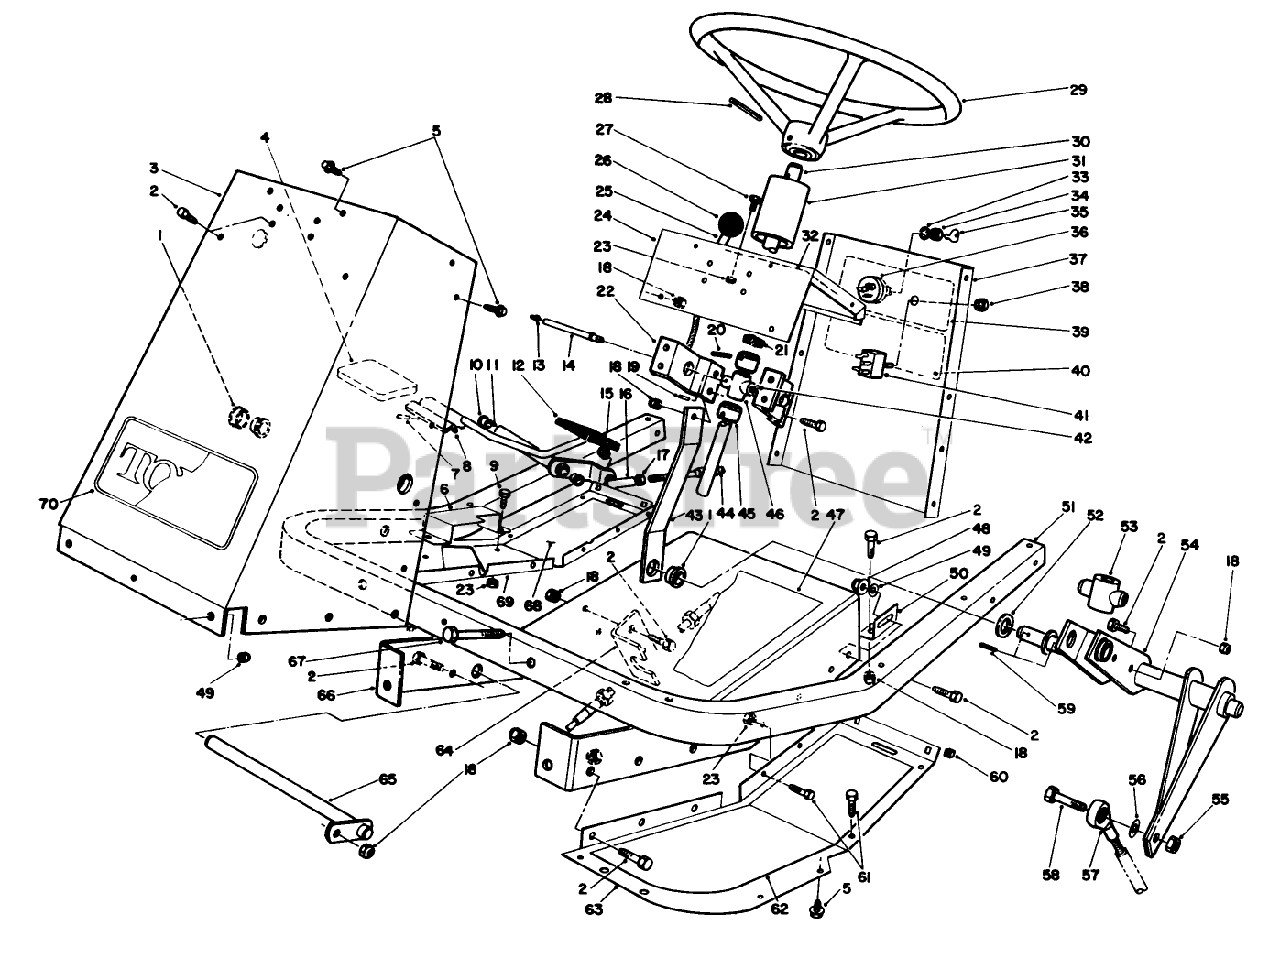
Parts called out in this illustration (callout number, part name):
1	BEARING-FLANGE
2	SCREW-HH
3	Tower-Front
4	FORWARD PEDAL PAD
5	SCREW-HHFTF
6	Footrest-Pedal
7	PIN-SPRING
8	ACCELERATOR PEDAL
9	SCREW-HH
10	BUSHING-FLANGE
11	Traction Pedal (Incl. Ref. #10)
12	REVERSE PAD
13	FITTING-GREASE
14	TUBE ZERK
15	NUT-LOCK
16	JOINT-BALL
17	NUT-JAM
18	NUT-LOCK, NI
19	3/32 X 9/16 ROLL PIN
20	PIN-SPRING
21	COVER-DUST
22	BRG SUPT BRKT
23	NUT-LOCK, NI
24	Tower-Top
25	CONTROL-CHOKE,THROTTLE
27	SCREW-HH
28	PIN-ROLL
29	WHEEL-STEERING
30	STEERING SHAFT
31	STRG. SHAFT COVER
32	THROTTLE DECAL
33	Washer-Lock
34	Nut-Hex
35	KEY-IGNITION
36	Switch-Ignition (Incl. Ref. #33-35)
37	REAR TOWER PANEL R
38	NUT
39	THROTTLE DECAL
40	SWITCH DECAL
41	Switch
42	WASHER-BELLEVILLE
43	Link-Steering
44	TRACT CONT.CABLE
45	STRG SHAFT COLLAR
46	BRG STEERING SHAFT
47	TUNNEL DECAL
48	NUT-HF
49	WASHER-PLAIN
50	TUNNEL BRKT
51	Frame-Footrest
52	WASHER-THRUST
53	STEER.SHAFT FOLLOWER
54	Follower Lever
55	NUT-HEX
56	WASHER-FLAT
57	BALL JOINT LH
58	SCREW-HH
59	PIN-ROLL
60	NUT-RETAINED
61	SCREW-HH
62	FOOT REST PAD LH
63	Footrest-L.H.
64	TRACT CABLE BRKT
65	PEDAL.SHAFT WA
66	Tunnel
67	SCREW-HH
68	FOOT REST PAD RH
69	Footrest-R.H.
70	DECAL
